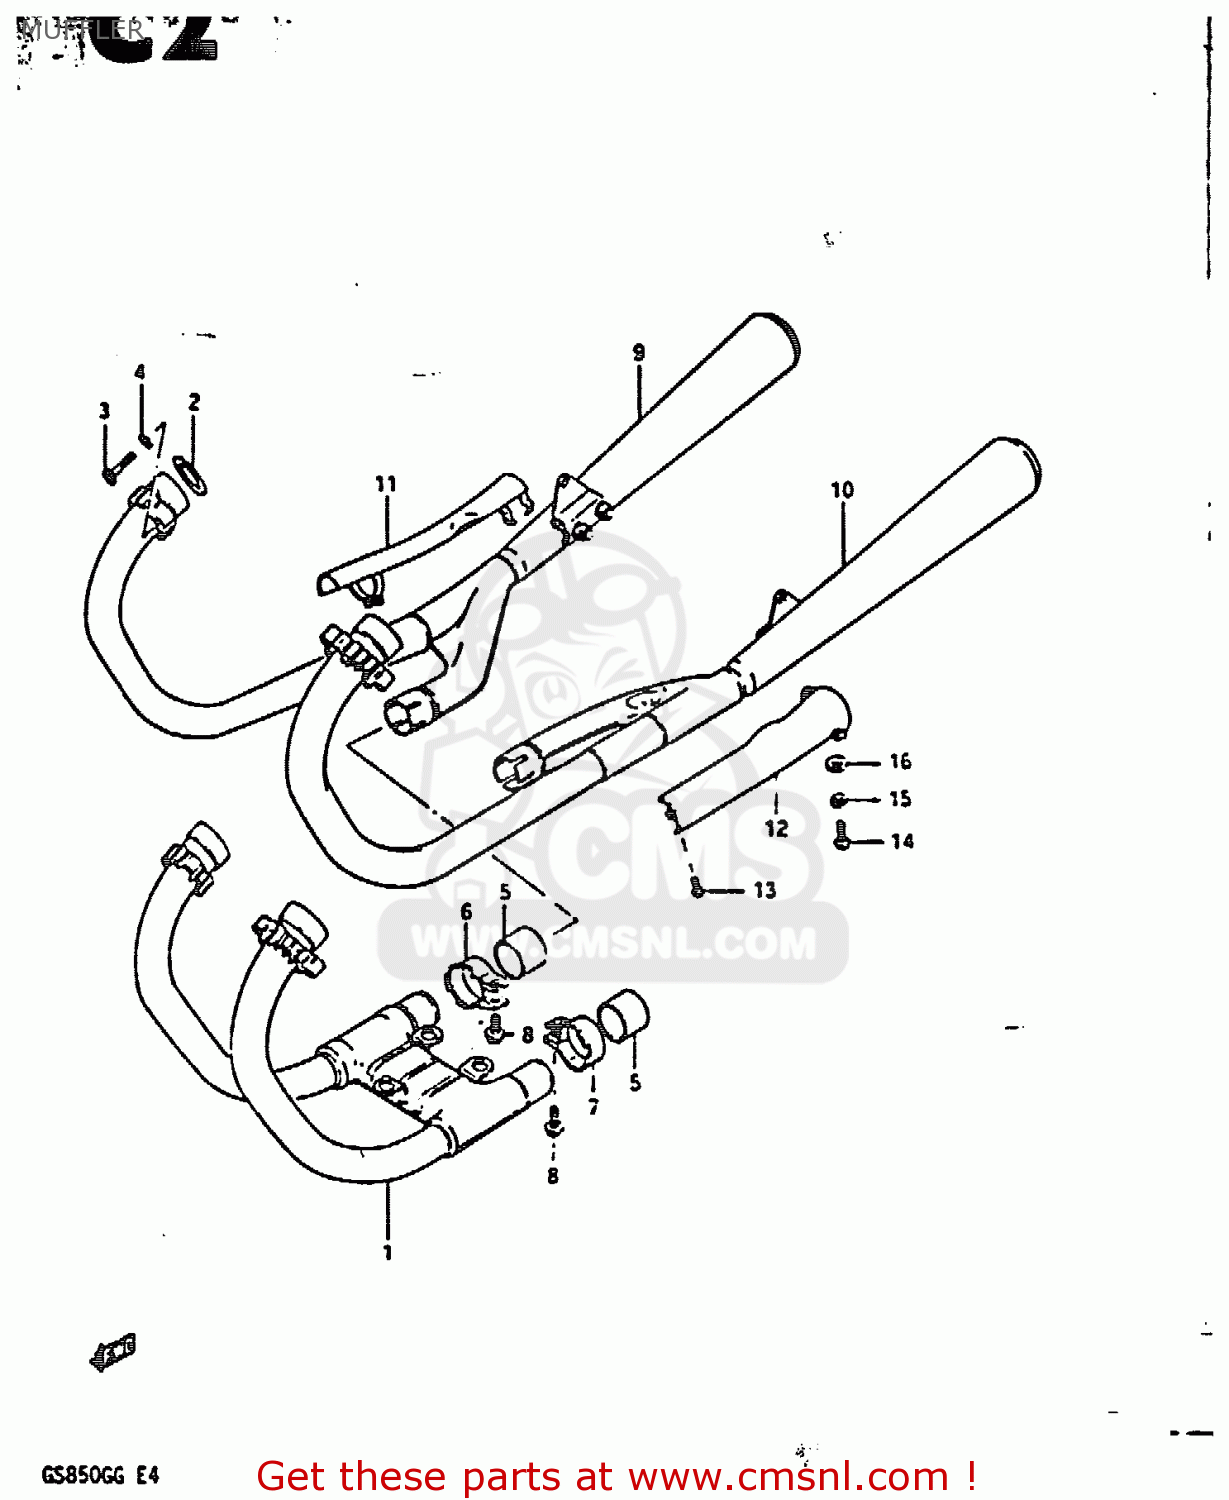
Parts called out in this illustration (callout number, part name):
1	PIPE,EXHAUST
2	GASKET,EXHAUST PIPE (NAS)
3	BOLT 8X40
4	LOCK WASHER
5	CONNECTOR,MUFFLER
6	CLAMP,MUFFLER CONNECTOR,R
7	CLAMP,MUFFLER CONNECTOR,L
8	BOLT
9	MUFFLER ASSEMBLY
10	MUFFLER ASSEMBLY
11	COVER,MUFFLER
12	COVER,MUFFLER,LEFT
13	SCREW
14	SCREW
15	LOCK WASHER
16	WASHER
